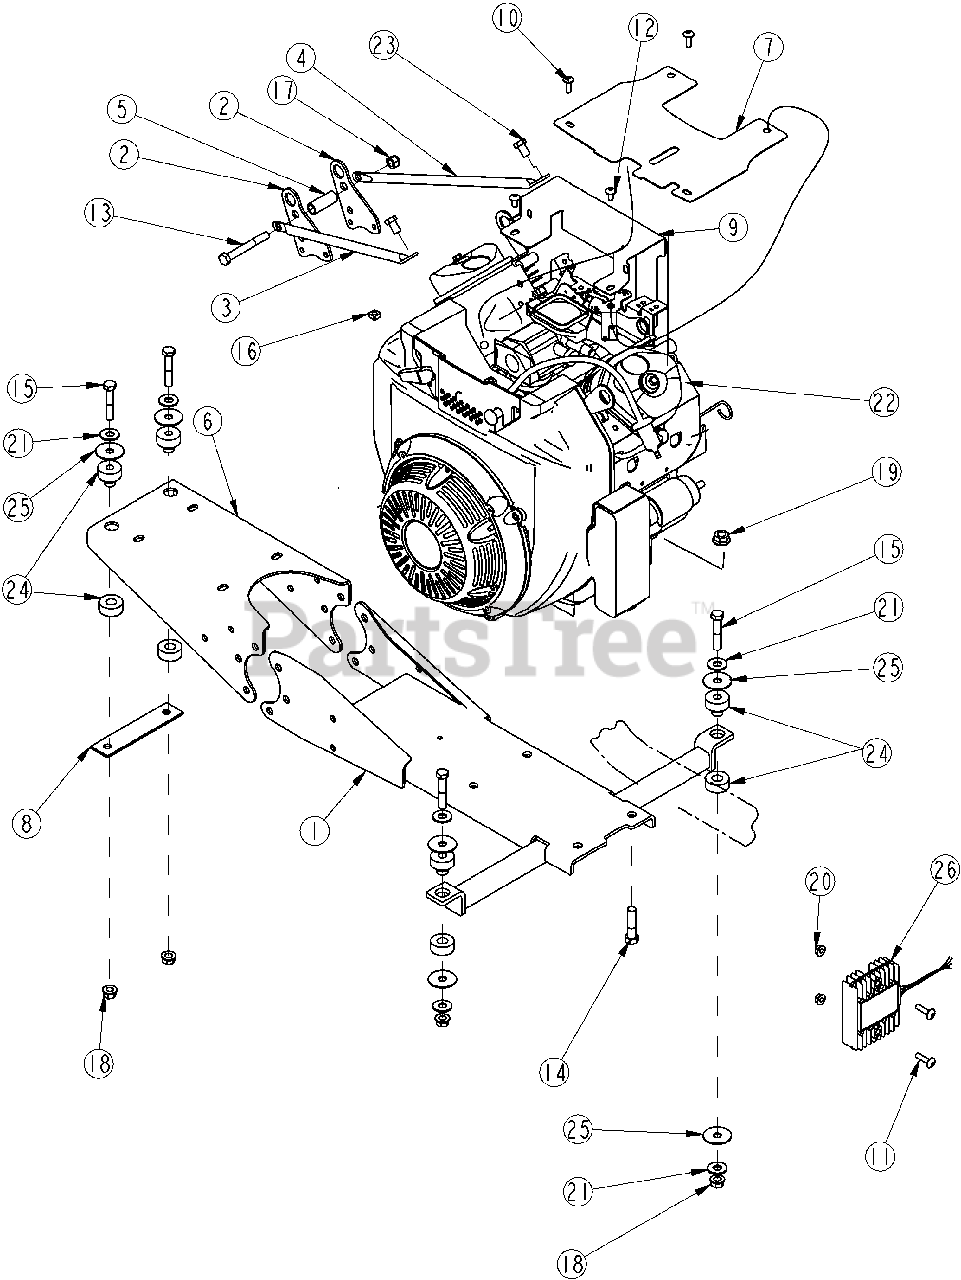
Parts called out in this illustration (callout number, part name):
1	ENGINE MOUNT WELDMENT
2	TRANS SUPPORT PLATE
3	ENGINE SUPPORT TUBE, RIGHT
4	ENGINE SUPPORT TUBE, LEFT
5	SPACER
6	TRANS MNT SUPPORT BRACKET ST
7	COVER/ENGINE TOP ASSEMBLY
8	SPACER PLATE, MOTOR MOUNT
9	COVER THROTTLE LINKAGE
10	TPHMS Y 1/4-20X3/4 YELLOW DIE
11	TPHMS Y 1/4-20X1 YELLOW DIE
12	TPHMS Y 1/4-20X1/2 YELLOW DIE
13	HHCS 3/8-16X3 GR5
14	HHCS 7/16-14X1 3/4 GR5
15	HHCS 3/8-16X2 GR5
16	NUT SQ 1/4-20 PLT
17	NUT LOCK 3/8-16 NYLON INSERT
18	NUT FLANGE LOCK 3/8-16 PLT
19	NUT HEX FLANGE LOC 7/16-14 PLT
20	NUT HEX FLNG T-LOCK 1/4-20 YLW
21	WASHER FLAT 3/8 USS PLT
22	HONDA ENGINE 20HP TRUCK Non Warranty Replacement Part
23	HFCS M8-1.25X20 10.9 HX FL ZN
24	MOUNT MOTOR H SYTLE
25	WASHER FENDER 1.5OD X.4IDX.06T
26	VOLTAGE REGULATOR FOR 826-41
